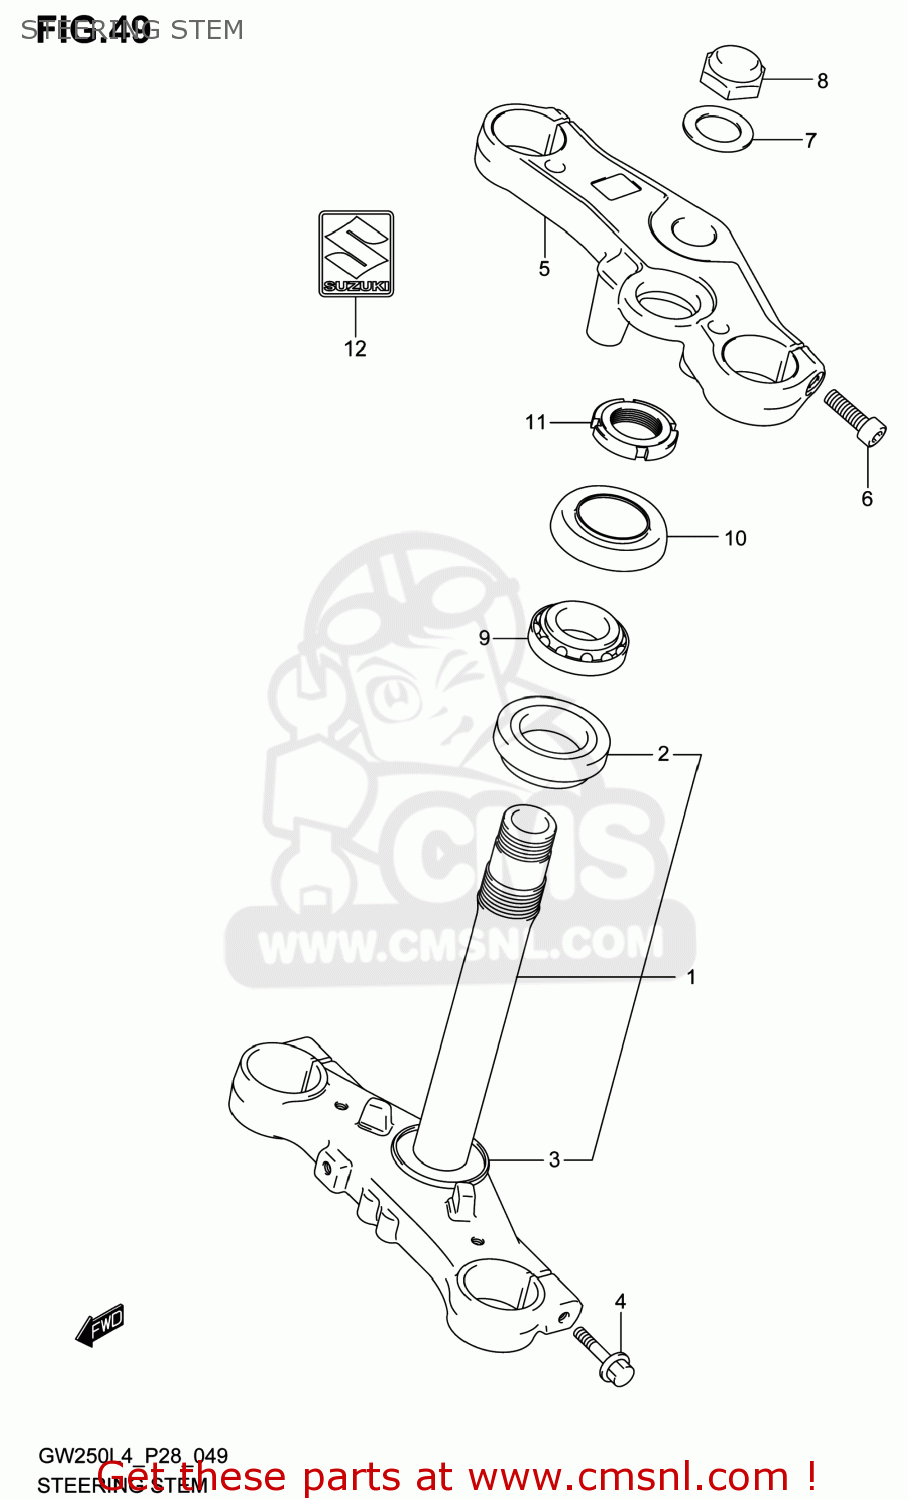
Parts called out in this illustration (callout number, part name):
1	BRACKET,UNDER
2	BEARING
3	SEAL,STEERING LWR
4	BOLT,BRACKET UNDER
5	BRACKET,UPPER
6	BOLT,BRACKET UPR
7	WASHER
8	NUT,CAP
9	BEARING(25X47X15)
10	SEAL,STEERING UPR DUST
11	NUT,STEERING STEM
12	EMBLEM,S
